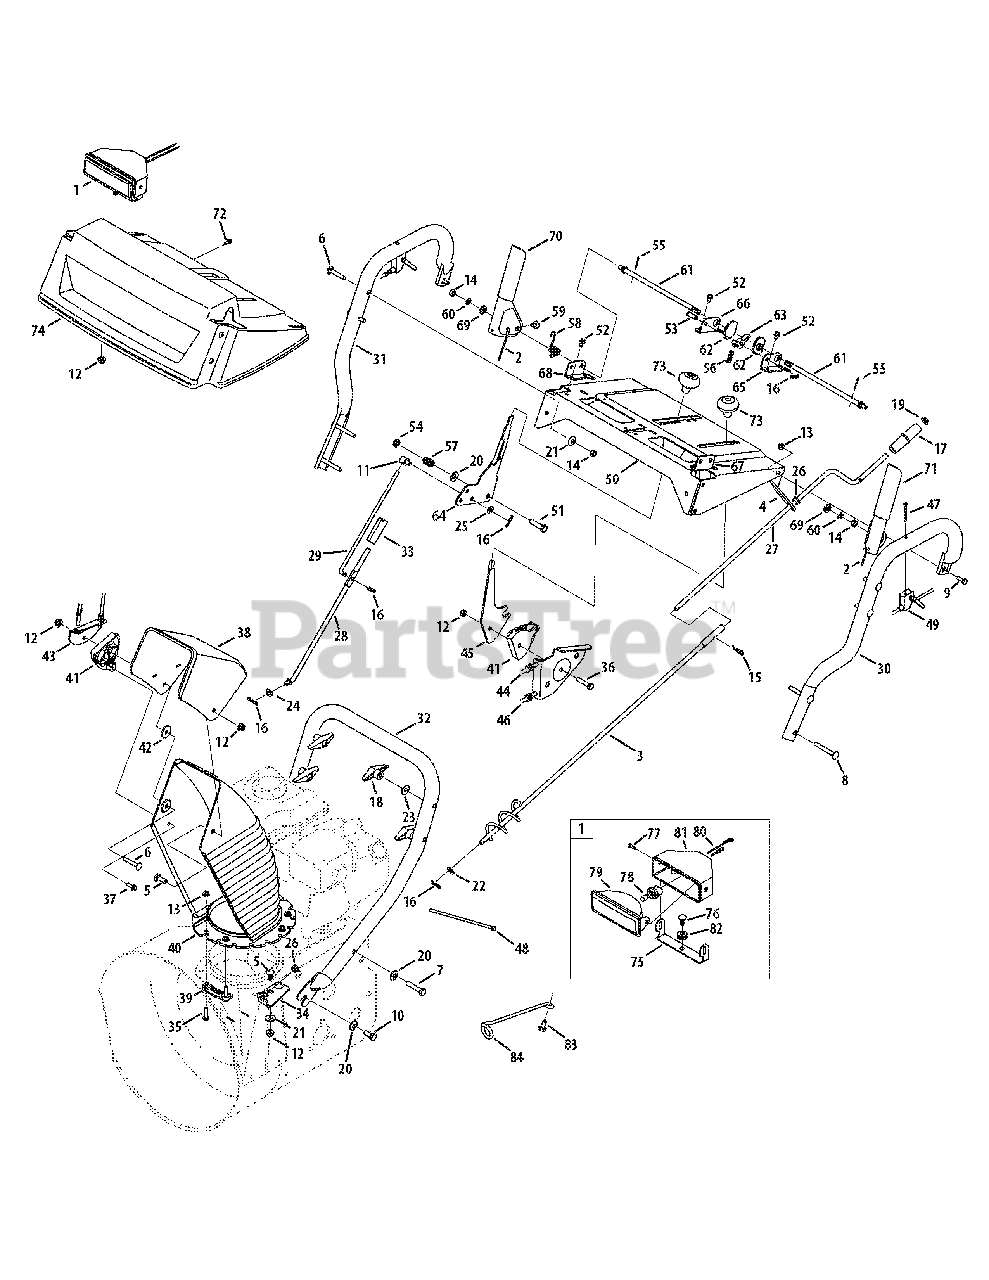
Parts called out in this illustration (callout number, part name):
1	Light Assembly w/ Harness
2	Cable Assembly, Auger/Drive
5	Screw, Carriage, 5/16-18 x 1.0
6	Screw, Carriage., 5/16-18 x 1.75
7	Screw, Hex Lock, 3/8-16 x 2.0 Gr5
8	Screw, Carriage., 5/16-18 x 2.5
9	Screw, Hex, 1/4-20 x .75
10	Screw, Hex Lock, 3/8-16 x 1.0 Gr5
11	Ferrule, 5/16-18 x .312 Dia
12	Nut, Flange Lock, 5/16-18
13	Nut, Hex Flange, 1/4-20
14	Nut, Hex Patch Lock, 5/16-18 Gr5
15	Pin, Internal Cotter
16	Pin, Internal Cotter
17	Knob, Crank
18	Knob, Wing Nut, 5/16-18
19	Cap, Push, 3/8
20	Washer, Bell, .375 x .87 x .063
21	Washer, Flat, .349 x .879 x .063
22	Washer, Flat, .375 x .738 x .063
23	Washer, Bell, .34 x .872 x .06
24	Washer, Flat, .344 x .688 x .065
25	Washer, Flat, .344 x .750 x .120
26	Bushing, Plastic, .38 ID
28	Rod, Lower Shift
29	Rod, Upper Shift
33	Connector, Shift Rod
35	Screw, Hex, 1/4-20 x 1.0
36	Screw, Hex, 5/16-18 x 1.5
37	Screw, Hx,1/4-15 x .75
38	Chute, Upper, 6.0
39	Flange Keeper, Chute
40	Chute, Lower
41	Cbl. Guide, Chute Tilt
42	Washer, Flat, .344 x 1.125 x .12
44	Cable, Chute Control, 66"
46	Cable, Chute Control w/Clip,
47	Screw, #10-24 x 1.75
48	Tie, Cable
49	Cable Assembly, Trigger
51	Screw, Hex, 3/8-24 x 1.5
52	Screw, Hex, 1/4-20 x .5
53	Pin, Clevis, .312 x 1.0
54	Nut, Insert, 3/8-24
55	Pin, Cotter, 3/32 x .75
56	Spring, Compression
57	Spring, Compression
58	Spring, Torsion
59	Bumper, Rubber
60	Washer, Lock, 5/16
62	Cam, Handle Lock
63	Pawl, Handle Lock
69	Washer, Flat, .35 Sq x .72 x .134
70	Handle, Engage, RH
71	Handle, Engage, LH
72	Screw, #10-16 x .625
73	Knob, Shift
74	Panel, Handle
75	Bracket, Lamp Mounting
76	Screw, Carriage, 5/16-18 x .75
77	Screw, Pan Head Machine
78	Lamp, Halogen, #890-12V-27W
79	Housing, Lamp w/Lens
80	Harness, Electrical
81	Housing, Lamp
83	Screw, 5/16-18 x .750
84	Cable Guide
